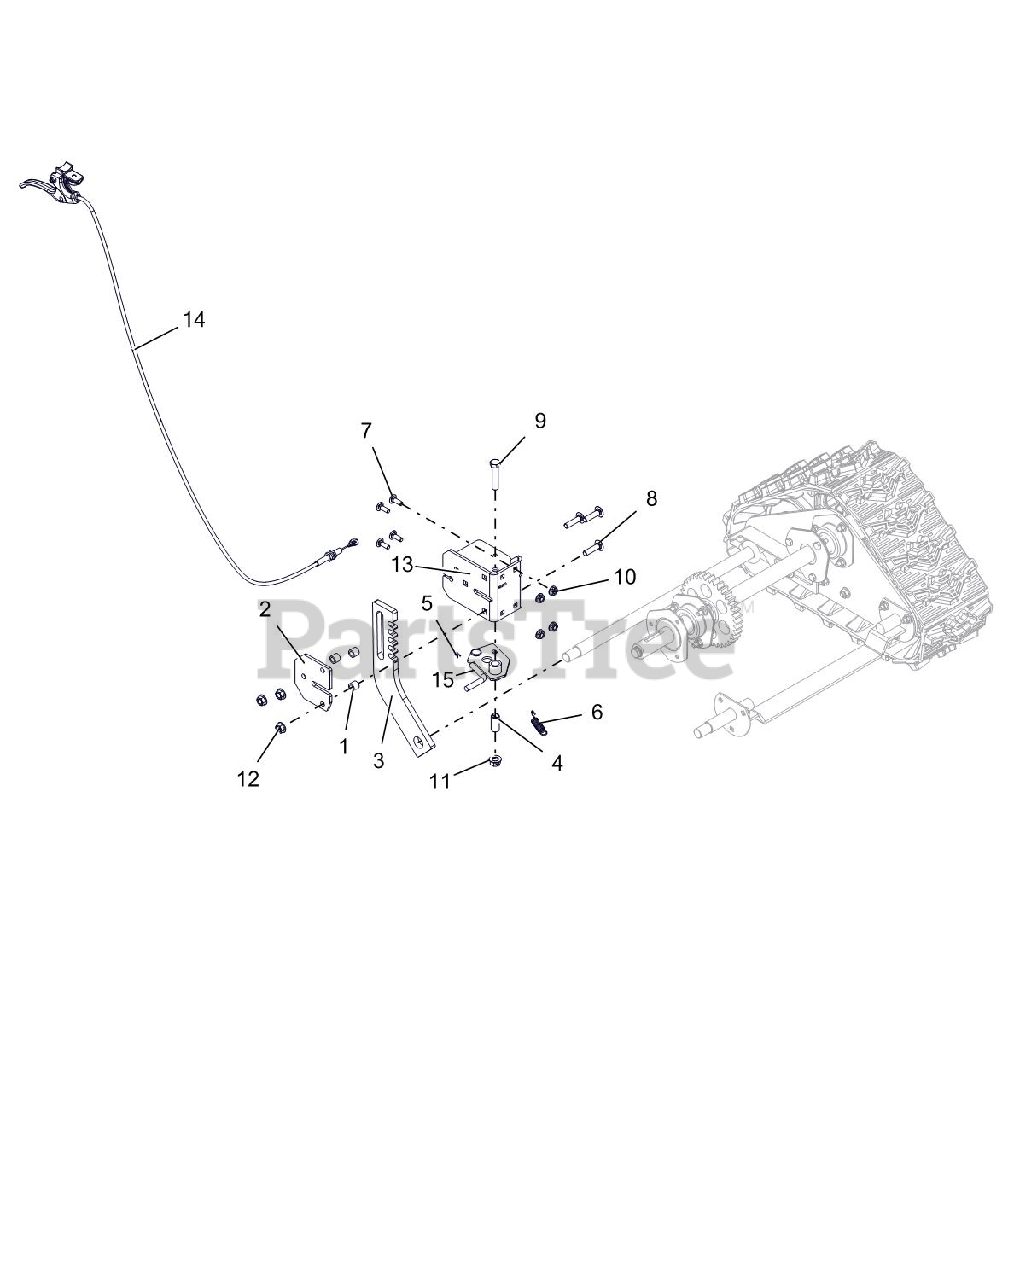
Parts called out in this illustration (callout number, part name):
1	SPACER .50 X .32 X .42
2	PLATE, HEIGHT ADJUSTER
3	STOP, HEIGHT ADJUSTER-CPT BLAC
4	BSHG-SLV .385X.500X1.045
5	PIN-HAIR INT .06X.18X.77
6	SPRING-EXT .047 X .438 X 1.85
7	@BLT-RDHDSQNK .25-20X.75 G5YZ
8	@BLT-RHDSHSQNK.31-18X1.25 G5YZ
9	@BLT-HEX .38-16X1.75 GR5 YWZC
10	@NUT-LK-CTR-FLG .25-20 YWZC
11	NUT-LK-CTR-FLG .38-16 YWZC
12	@NUT-LK-TOP-FLG .31-18 YWZC
13	BRACKET, HEIGHT ADJUSTER
14	CABLE, TRACK REMOTE
15	LOCK,HEIGHT ADJUSTER TRIGGER
